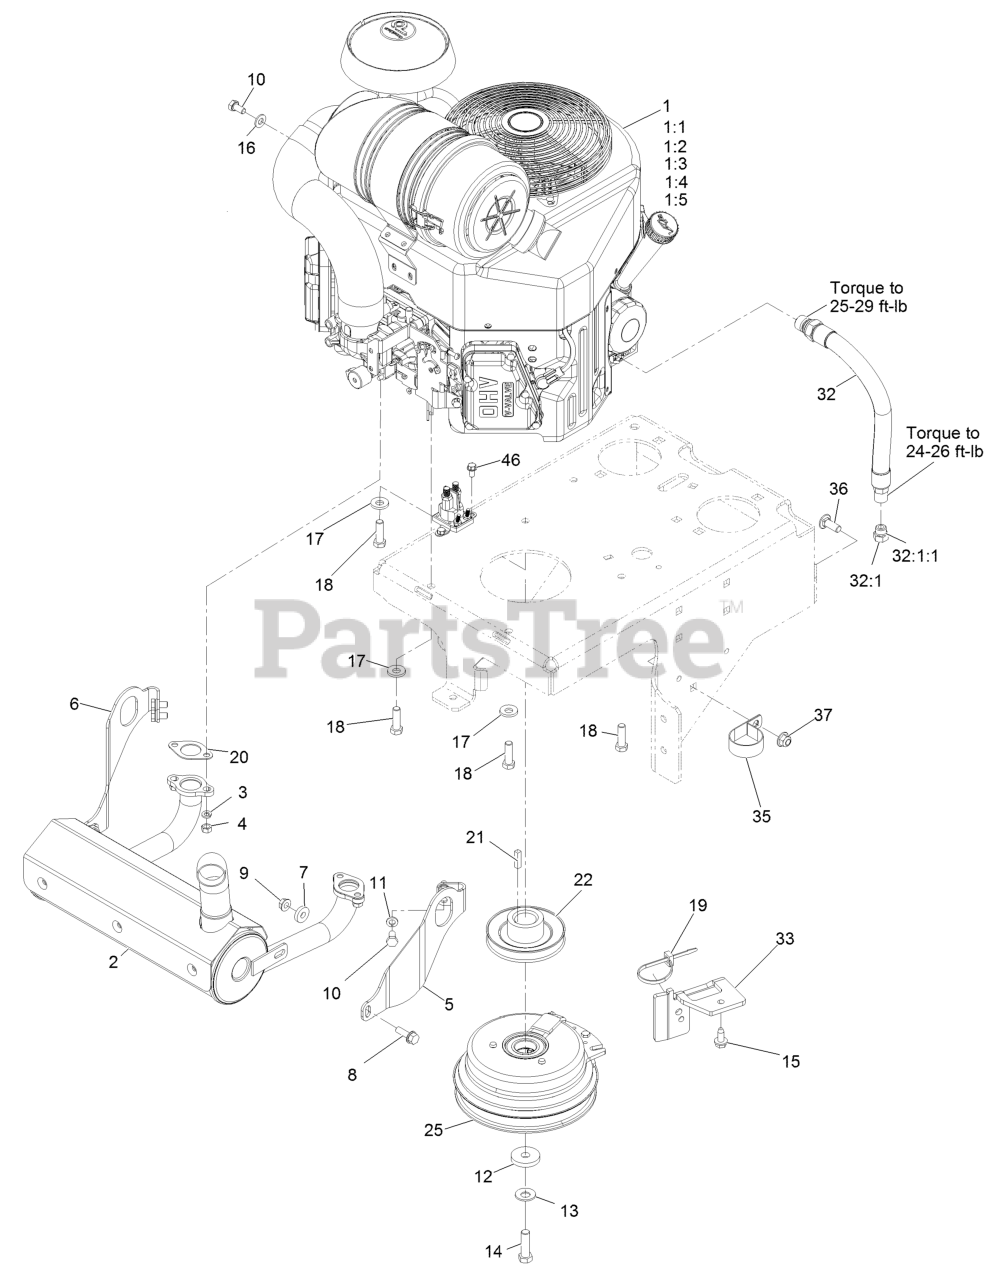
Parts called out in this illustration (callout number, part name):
1:1	FILTER-OIL
1:3	ELEMENT-FILTER, AIR (OUTE
1:4	ELEMENT-FILTER, AIR (INNE
2	MUFFLER, KAWASAKI, 22-26
3	WASHER-LOCK
5	BRACKET-MUFFLER MOUNT, LH
6	BRACKET-MUFFLER MOUNT, RH
8	SCREW-HHF
10	SCREW-HH
11	WASHER-LOCK
12	WASHER
13	WASHER-SPRING
14	SCREW-HH
15	Screw-HWH 5/16-18 X 3/4 Tf
16	WASHER-PLAIN
17	WASHER-BELLEVILLE
18	SCREW-HH
19	TIE-CABLE
20	GASKET-EXHAUST
25	CLUTCH-200 FT-LB, 1.125 B
32	ENGINE OIL DRAIN HOSE ASM
32:1	PLUG-HH
32:1:1	O-RING
33	BRACKET-ANCHOR, CLUTCH
35	CLAMP-R
36	SCREW-CARR
37	NUT-HF, NI
46	SCREW-HWH
